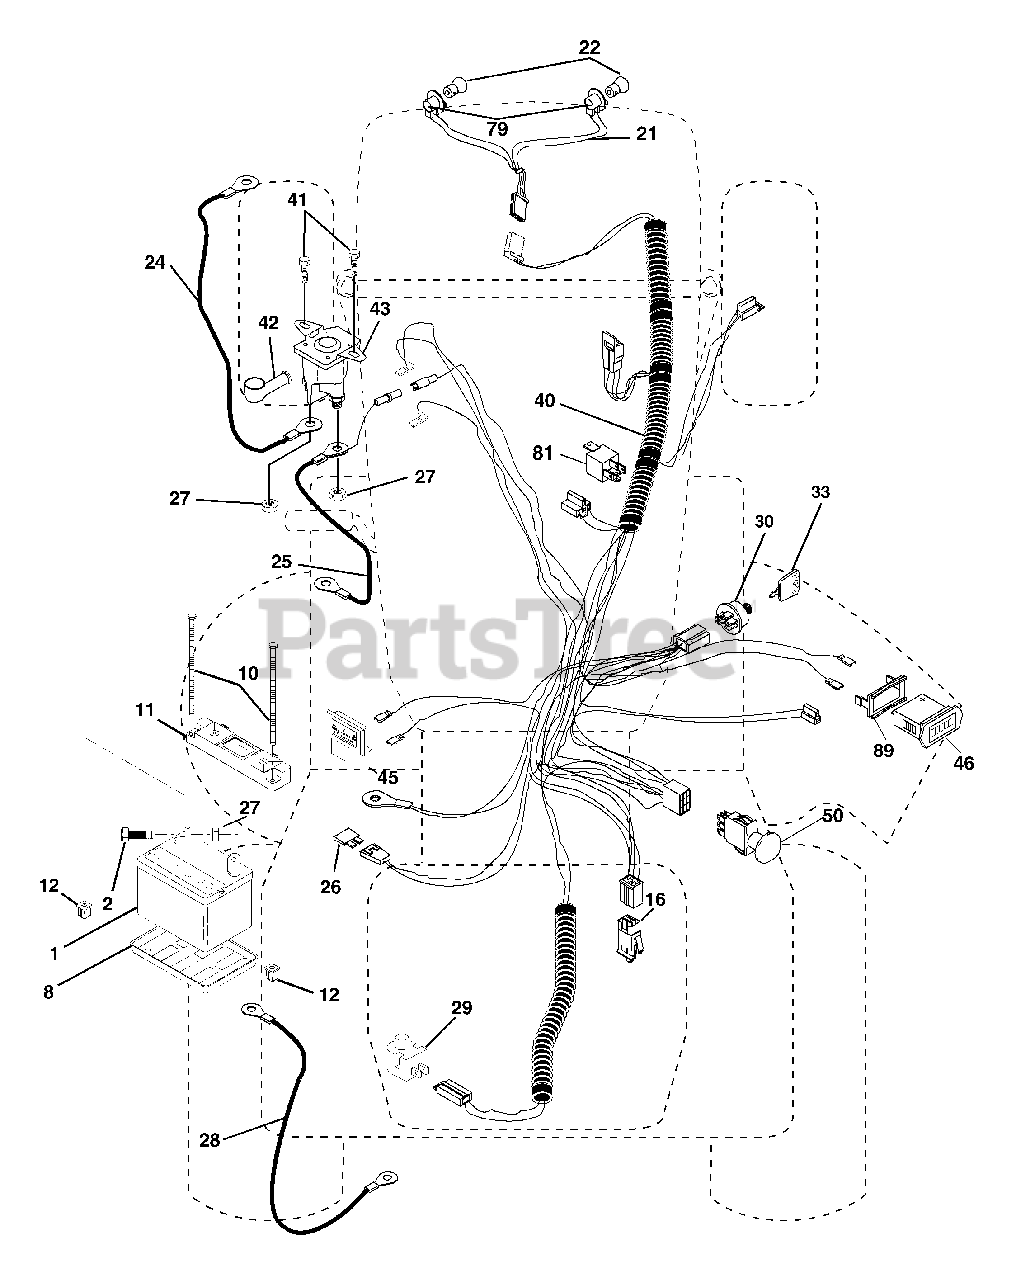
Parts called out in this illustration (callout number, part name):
1	Battery
2	Bolt Hex Head 1/4-20 x 3/4
8	Tray, Battery
10	Bolt Btr Frt 1/4-20 x 7.5 zinc
11	Holdown Battery Front Mount
12	Nut Push Nylon 1/4"
16	Switch Interlock Push-In
21	Harness Headlight w/Bulbs
22	Bulb Light
24	Cable, Battery
25	Cable, Battery
26	Fuse
27	Nut Keps Hex 1/4-20 unc
28	Cable, Ground
29	Switch, Plunger
30	Switch, Ign
33	Key
40	Harness, Ignition
41	Screw 1/4-20 x 1/2
42	Cover, Terminal Red
43	Solenoid
45	Ammeter
46	Hourmeter Snap-In
50	Switch, PTO
79	Socket, Light Bulb
81	Relay Asm.
89	Bracket Snap-In
